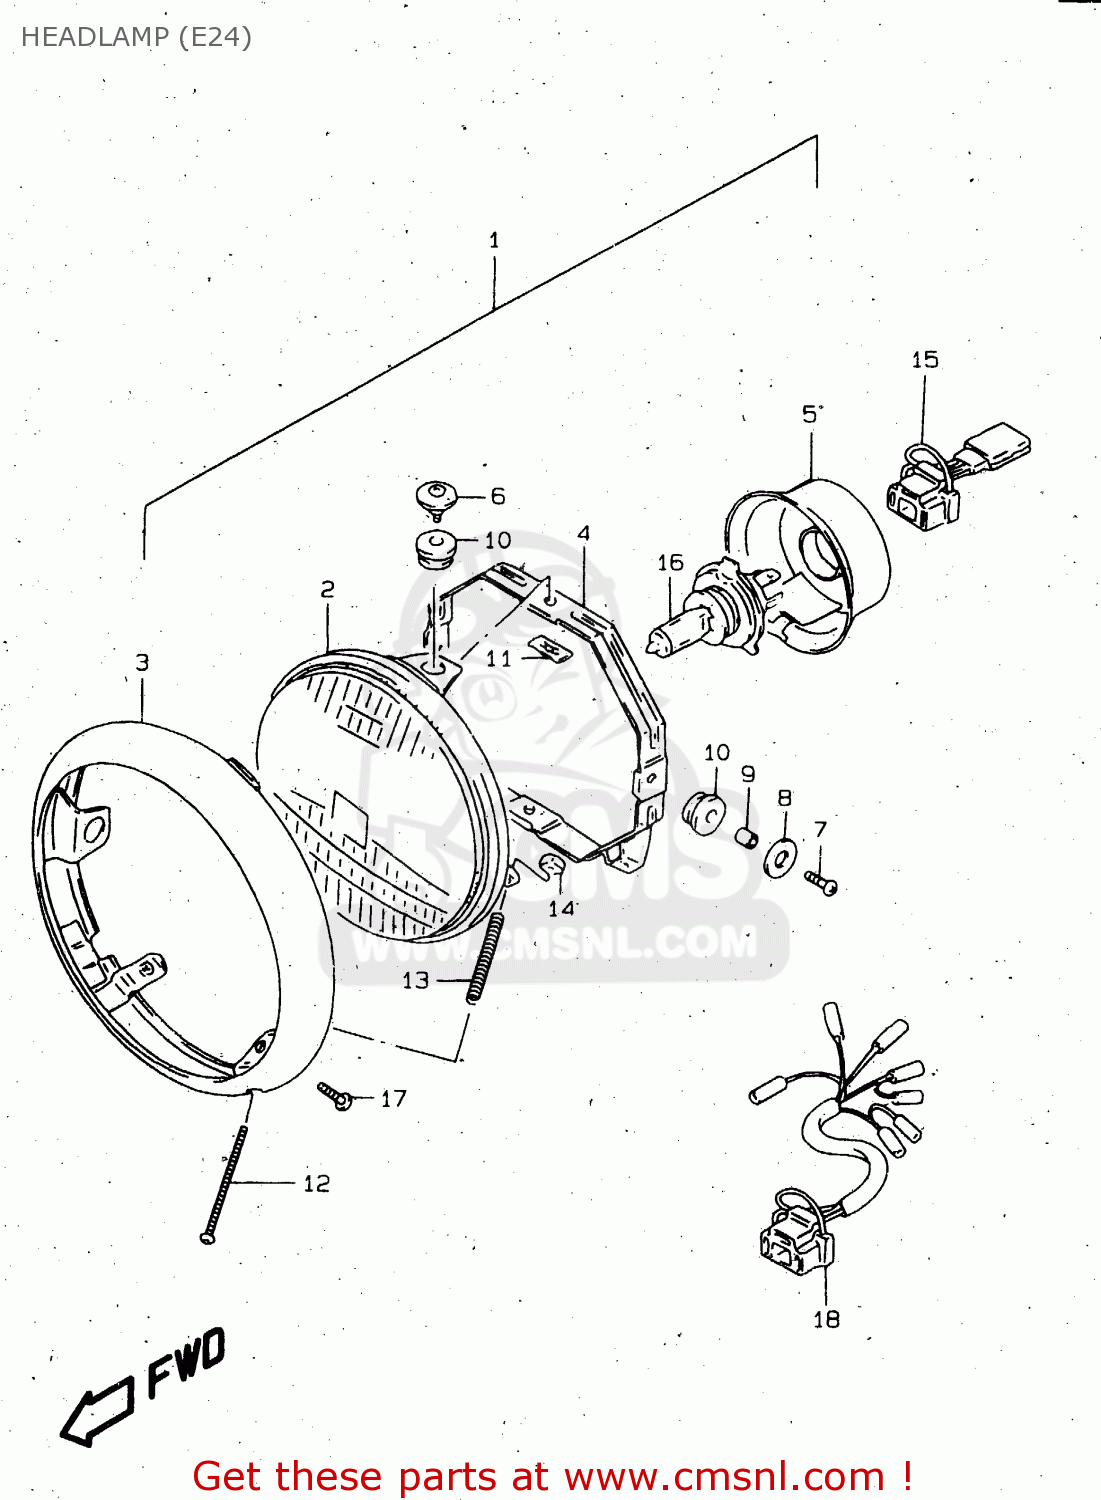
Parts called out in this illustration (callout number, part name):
1	HEADLAMP ASSY
2	UNIT,LAMP
3	RIM
4	RING,MOUNTING
5	COVER,SOCKET
6	SCREW,MOUNTING
7	SCREW
8	WASHER(5.5X18X1)
9	SPACER
10	CUSHION
11	NUT
12	SCREW,ADJUSTING(4X50)
13	SPRING
14	NUT
15	SOCKET
16	BULB(12V60/55W,H4)
17	SCREW
18	WIRE,HEADLAMP LEAD
